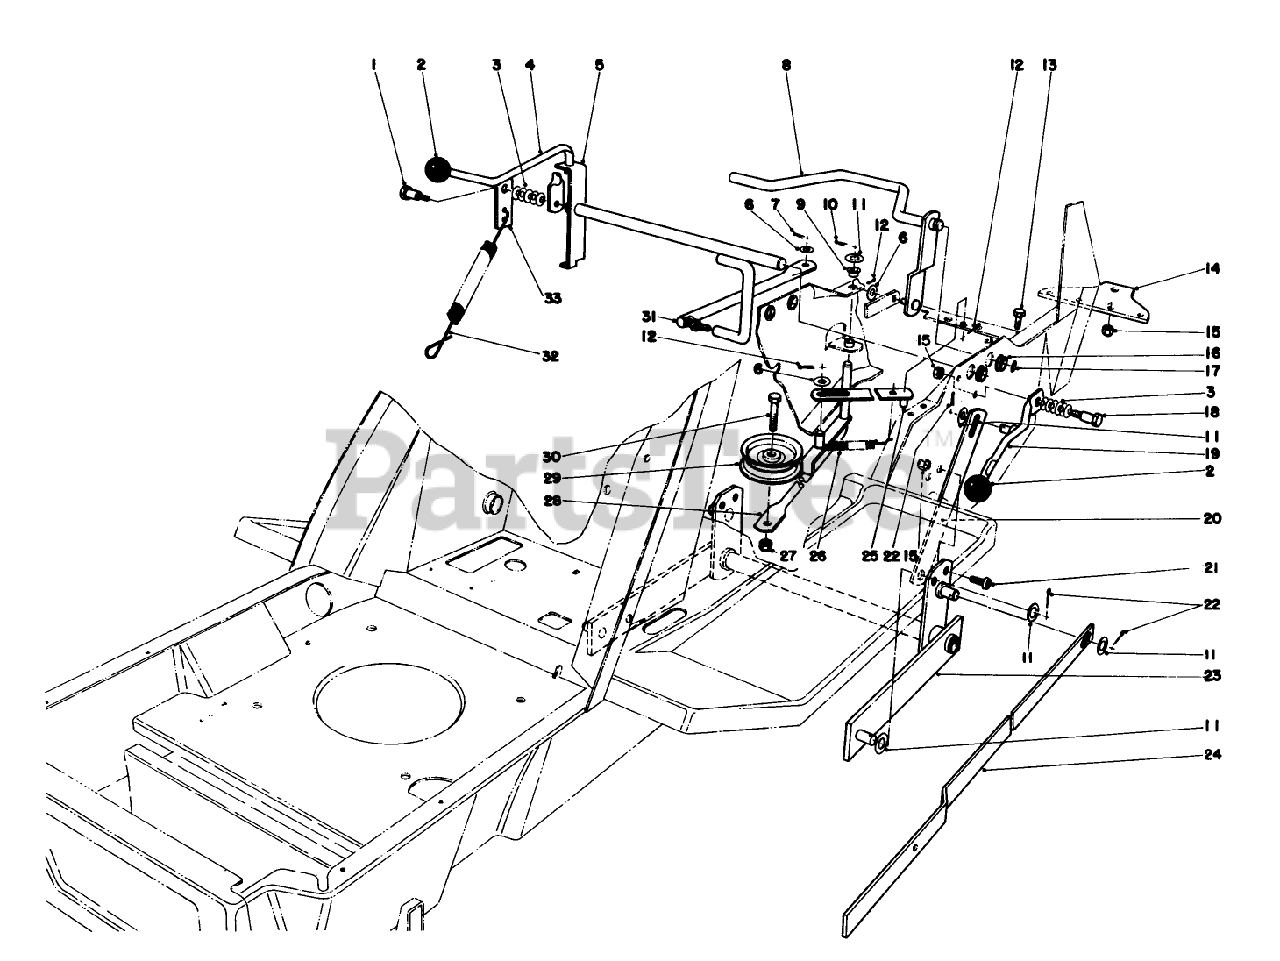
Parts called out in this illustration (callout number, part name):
1	BOLT-SHOULDER
3	WASHER-BELLEVILLE
6	WASHER-PLAIN
7	PIN-COTTER
9	BUSHING-NYLINER
10	PIN-COTTER
11	WASHER-FLAT
12	PIN-COTTER
13	SCREW-HHF
15	NUT-LOCK, NI
17	E-RING
18	SHOULDER BOLT
21	SCREW-HSBH
22	PIN-COTTER
27	NUT-LOCK, CONE
28	IDLER ARM WA *BO
30	SCREW-HH
31	SHIFT ARM *BO
